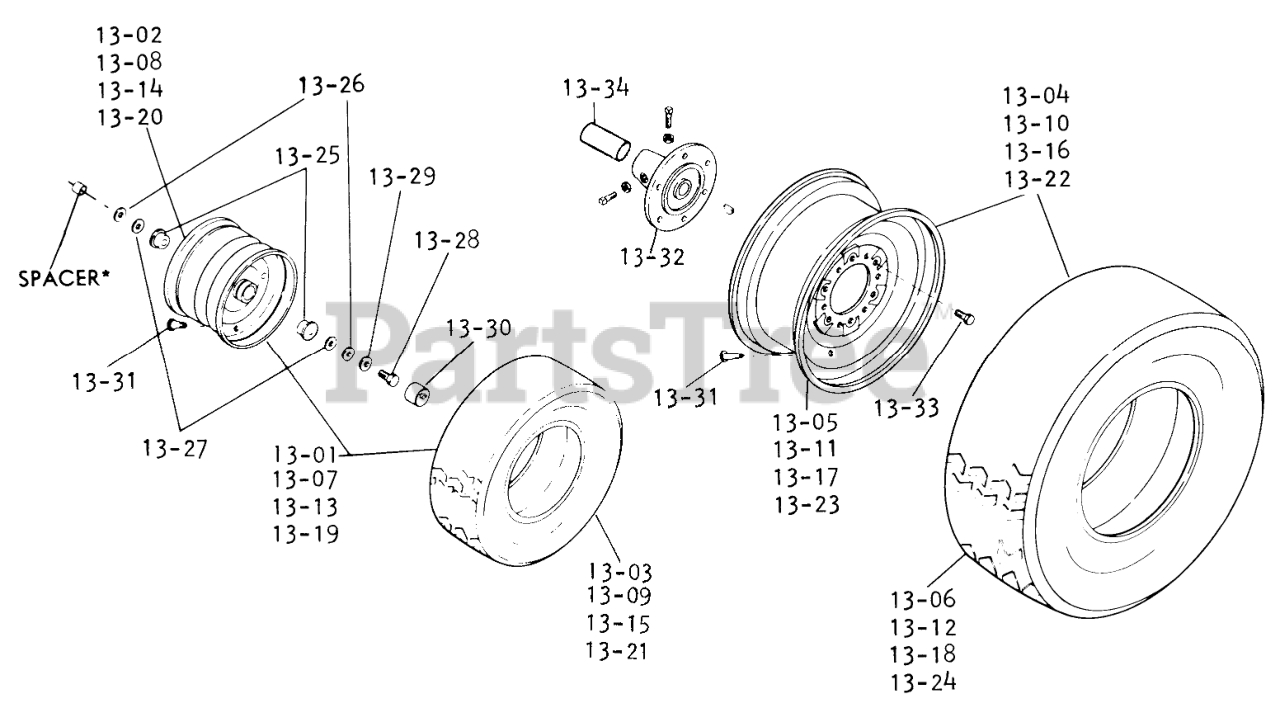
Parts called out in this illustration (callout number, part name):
13-01	Wheel & Tire Assy.-Front 18 X 6.50-8
13-02	Wheel
13-03	TIRE
13-04	Rear Wheel and Tire Assy Turf
13-05	Rear Wheel
13-06	Tire 27 x 9.50-15
13-07	Wheel & Tire Assy.-Front 18 X 8.50-8
13-08	Wheel
13-09	TIRE 18 X 8.50 X 8
13-10	Rear Wheel & Tire Turf
13-11	Wheel 12 x 10.5 PC
13-12	Tire, Extra Width Traction
13-13	Wheel & Tire Assy.-Front 18 X 6.50-8
13-14	Wheel
13-15	TIRE
13-16	Wheel & Tire Assy.-Rear 27 X 8.50-15
13-17	Rear Wheel
13-18	Rear Tire 27 x 8.50-15 Cleat
13-19	Wheel & Tire Assy.-Front 18 X 8.50-8
13-20	Wheel
13-21	TIRE 18 X 8.50 X 8
13-22	Rear Wheel & Tire Cleat
13-23	Wheel 12 x 10.5 PC
13-24	Tire, Extra Width Cleat
13-25	Bearing
13-26	Washer-. 050" Shim
13-27	Washer-. 015" Shim
13-28	Bolt 3/8-16 x 7/8
13-29	WASHER
13-30	HUBCAP
13-31	VALVE
13-32	REAR HUB R
13-33	LUG BOLT WHEEL 7/162
13-34	Axle Cover Tube
